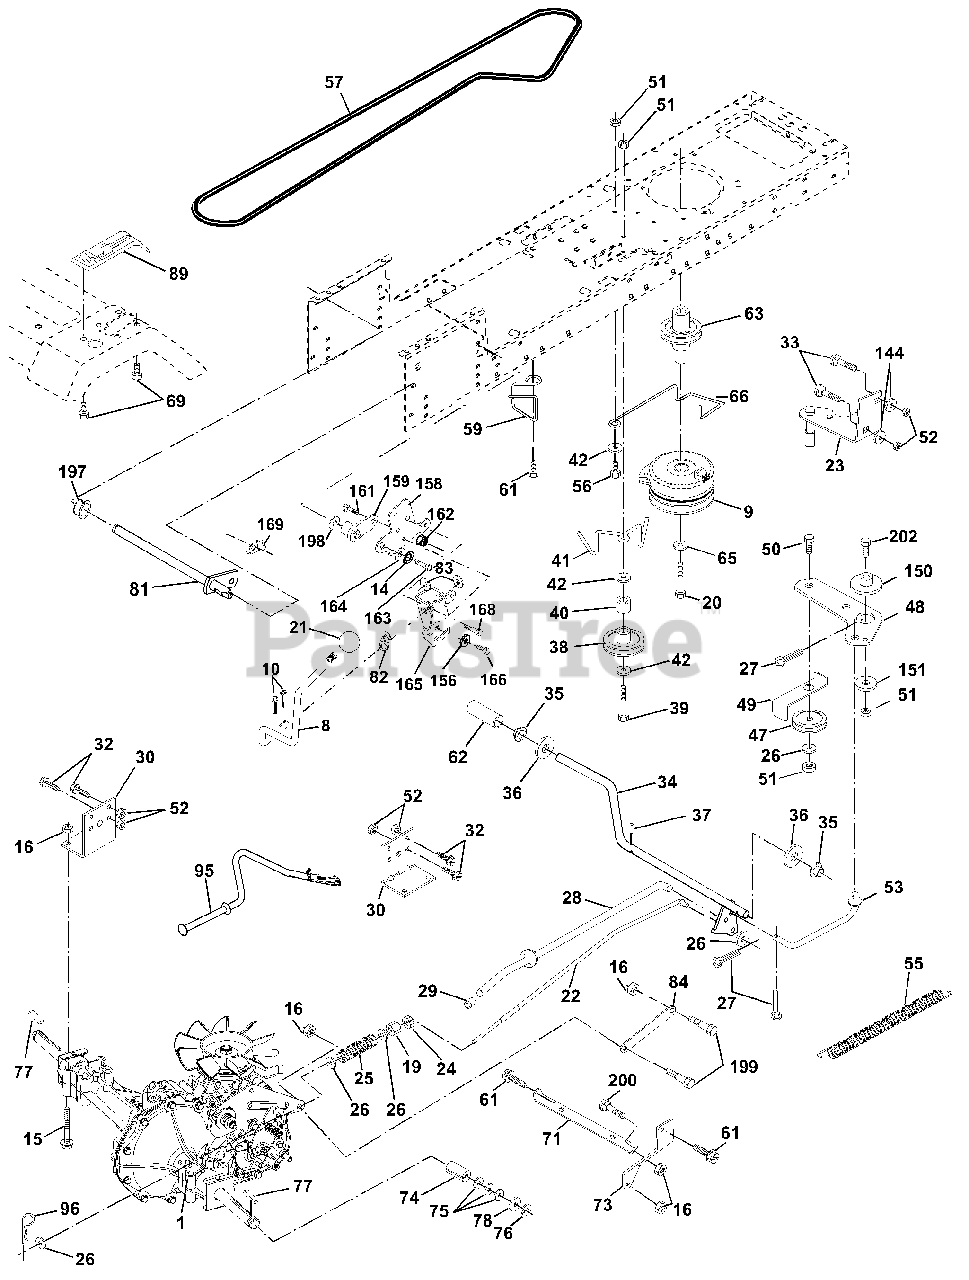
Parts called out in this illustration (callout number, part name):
8	Rod Shift Fender
9	Clutch Electric
10	Pin Cotter 1/8 x 1 CAD
14	Washer Lock Hvy Helical
15	Bolt Hex Flghd 5/16-18 Gr. 5
16	Nut Lock Hex W/Ins. 5/16-18 Unc
19	Nut Lock Hex W/Wsh 3/8-16 Unc
20	Bolt, Hex 7/16-20 x 4-1/4
21	Knob Deluxe
22	Rod, Brake Hydro
23	Bracket Asm. Anti-Rot EVX
24	Locknut
25	Spring, Brake Rod
26	Washer
27	Pin Cotter 1/8 x 3/4 CAD.
28	Rod, Parking Brake
29	Cap, Parking Brake
30	Bracket, Transaxle
32	Bolt Hex Hd 5/16-18 Unc x 3/4
33	Bolt Carriage 5/16-18 UNC x 3/4
34	Shaft, Foot Pedal
35	Bearing, Nylon
36	Washer
37	Pin, Roll
38	Pulley, Idler, Flat
39	Bolt
40	Spacer Split
41	Keeper, Belt Idler Fool-Proof
42	Washer 13/32 x 13/16 x 12 Gauge
47	Pulley, Idler, V-Groove
48	Bellcrank Clutch Grnd Drv Stl
49	Retainer, Belt
50	Bolt
51	Nut
52	Nut Crown Lock 5/16-18
53	Link, Clutch
55	Spring, Return, Clutch
56	Bolt
57	V-Belt, Ground Drive
59	Keeper, Center Span
61	Screw 3/8-16 x 3/4
62	Cover, Pedal
63	Pulley, Engine
65	Washer
66	Keeper Belt Engine Hydro
69	Screw Hexwsh Hi-Lo 1/4-1/2 UNC
71	Strap Torque Lh Hydro
73	Strap Torque Rh Hydro
74	Spacer, Axle
75	Washer 25/32 x 1-1/4 x 16 Ga.
76	E-Ring
77	Key, Square
78	Washer 25/32 x 1-5/8 x 16 Ga.
81	Shaft Asm. Cross Hydro
82	Spring Torsion T/A
83	Washer 17/32 x 3/4 x 16 Ga.
84	Link Transaxle
89	Console, Shift
95	Control Asm. Bypass Hydro
96	Retainer Spring 1" Zinc/Cad
144	Washer 11/32 x 5/8 x 16 Ga.
150	Bushing Bellcrank Grd Drive
151	Washer 13/32 x 2 x 10 Ga.
156	Washer Srrted 5/16ID x 1.125
158	Bracket Shift Mount
159	Hub Tapered Flange Shift Lt
161	Bolt Rdhd Sqnk 1/4-20 x 3/4 Gr. 5
162	Nut Crownlock 1/4-20 Unc
163	Bolt Hex Fin 1/4-20 Unc x 1 Gr. 5
164	Washer 5/8 x .281 x 10 Ga
165	Bracket Pivot Lever
166	Screw 5/16-18 x 5/8
168	Bolt Shoulder 5/16-18 x .561
169	Plate Fastening Lt\
197	Nyliner Snap-In 5/8" ID
198	Washer Nyliner 7/8 ID x .105
199	Bolt Shoulder 5/16-18 Unc
200	Bolt Rdhd Sqnk 5/16-18 UNC x 1
202	Bolt Carr Sh 3/8-16 x 1-1/2 Gr.5
